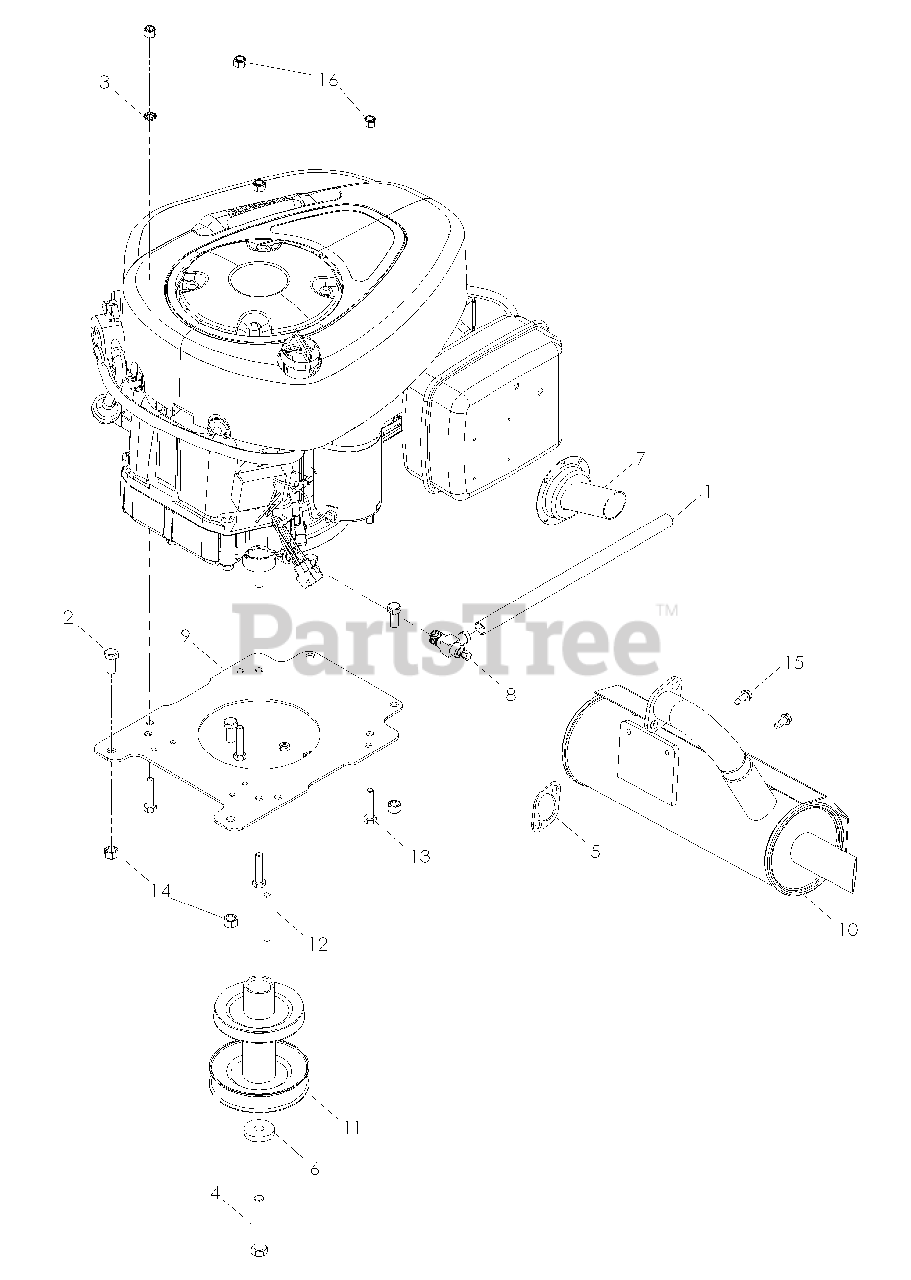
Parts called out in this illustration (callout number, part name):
1	OIL DRAIN HOSE
2	HCS 3/8-16 X 7/8 GR 5 ZD
3	WASHER 5/16 EXT STAR
4	HCS 7/16-20 X 2-3/4
5	SPACER, EXHAUST
6	WASHER .43X1.38X.25
7	MUFFLER EXTENSION
8	OIL DRAIN
9	ENGINE PLATE
10	MUFFLER 13HP
11	PULLEY ENGINE 30"
12	KEY 1/4 SQ X 2-1/2
13	CAPSCREW 5/16 X 1/1/2 HEX HEAD
14	NUT 3/8-16 NYLOC
15	SCREW 1/4 X 5/8
16	NUT 5/16 NYLOC
